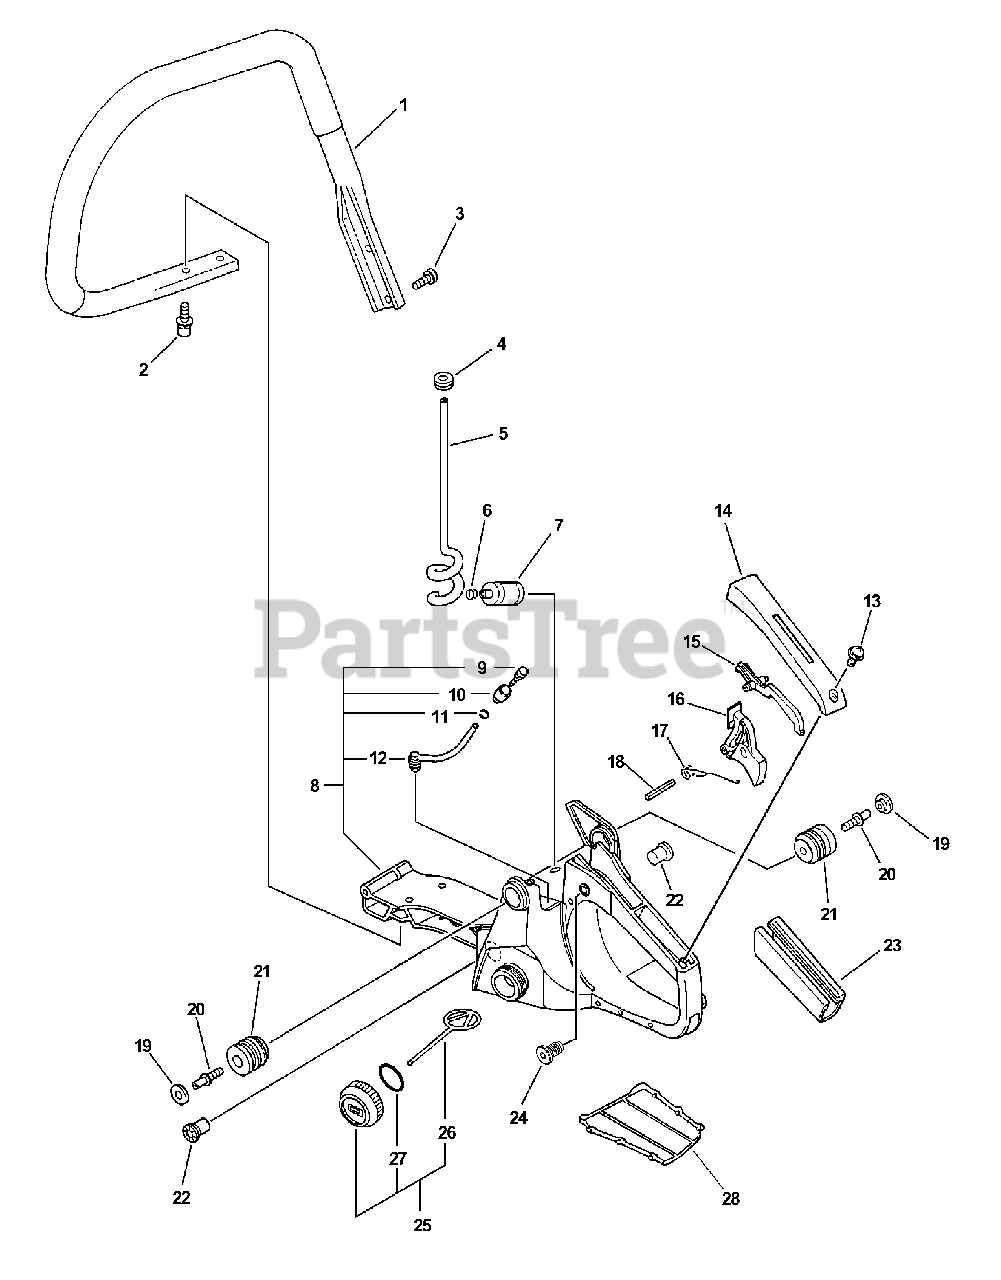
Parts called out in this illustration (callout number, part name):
1	HANDLE - FRONT
2	SCREW - 5X16
3	SCREW - 5X20 -- TAPPING
5	PIPE, FUEL - SPIRAL
6	CLIP - 6.5
7	FILTER, FUEL
8	HANDLE ASSY - REAR
9	VENT, FUEL TANK
10	COVER, VENT
11	CLIP - 6.5
12	PIPE - VENT
13	SCREW - 4X14
14	COVER, HANDLE
15	LEVER, TRIGGER LOCKOUT
16	TRIGGER, THROTTLE
17	SPRING, TRIGGER
18	PIN - SPRING -- 4X30
19	CAP, CUSHION
23	GRIP, HANDLE
25	CAP ASSY - ORANGE
26	CONNECTOR, CAP
27	O-RING - 22
28	SHIELD, SNOW
